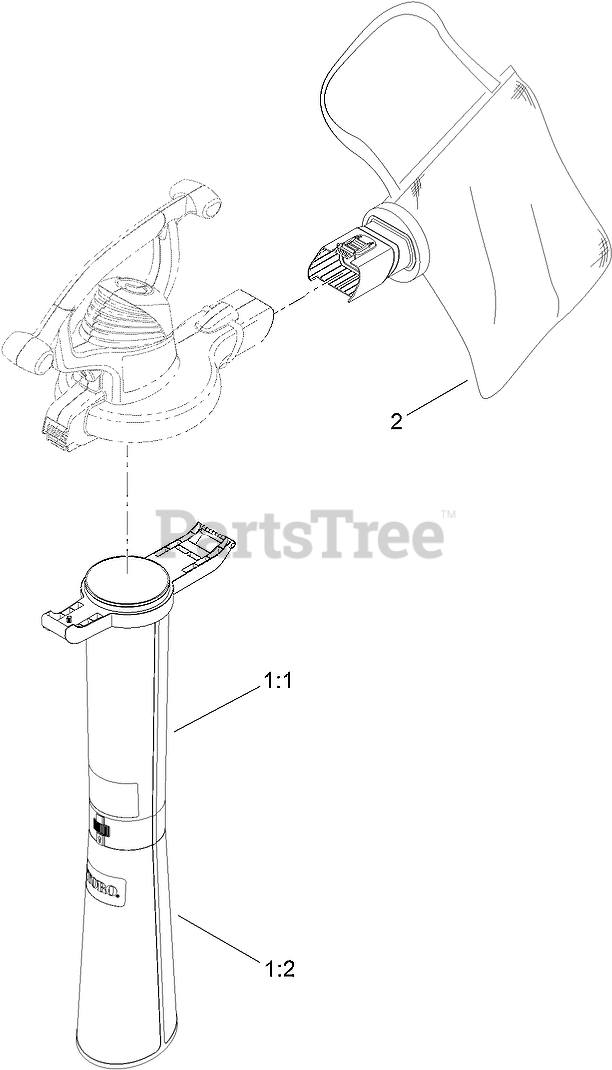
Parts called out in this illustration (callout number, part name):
1	Vac Tube ASM
1:1	TUBE-VACUUM, UPPER
1:2	TUBE-VACUUM, LOWER
2	BAG ASM
